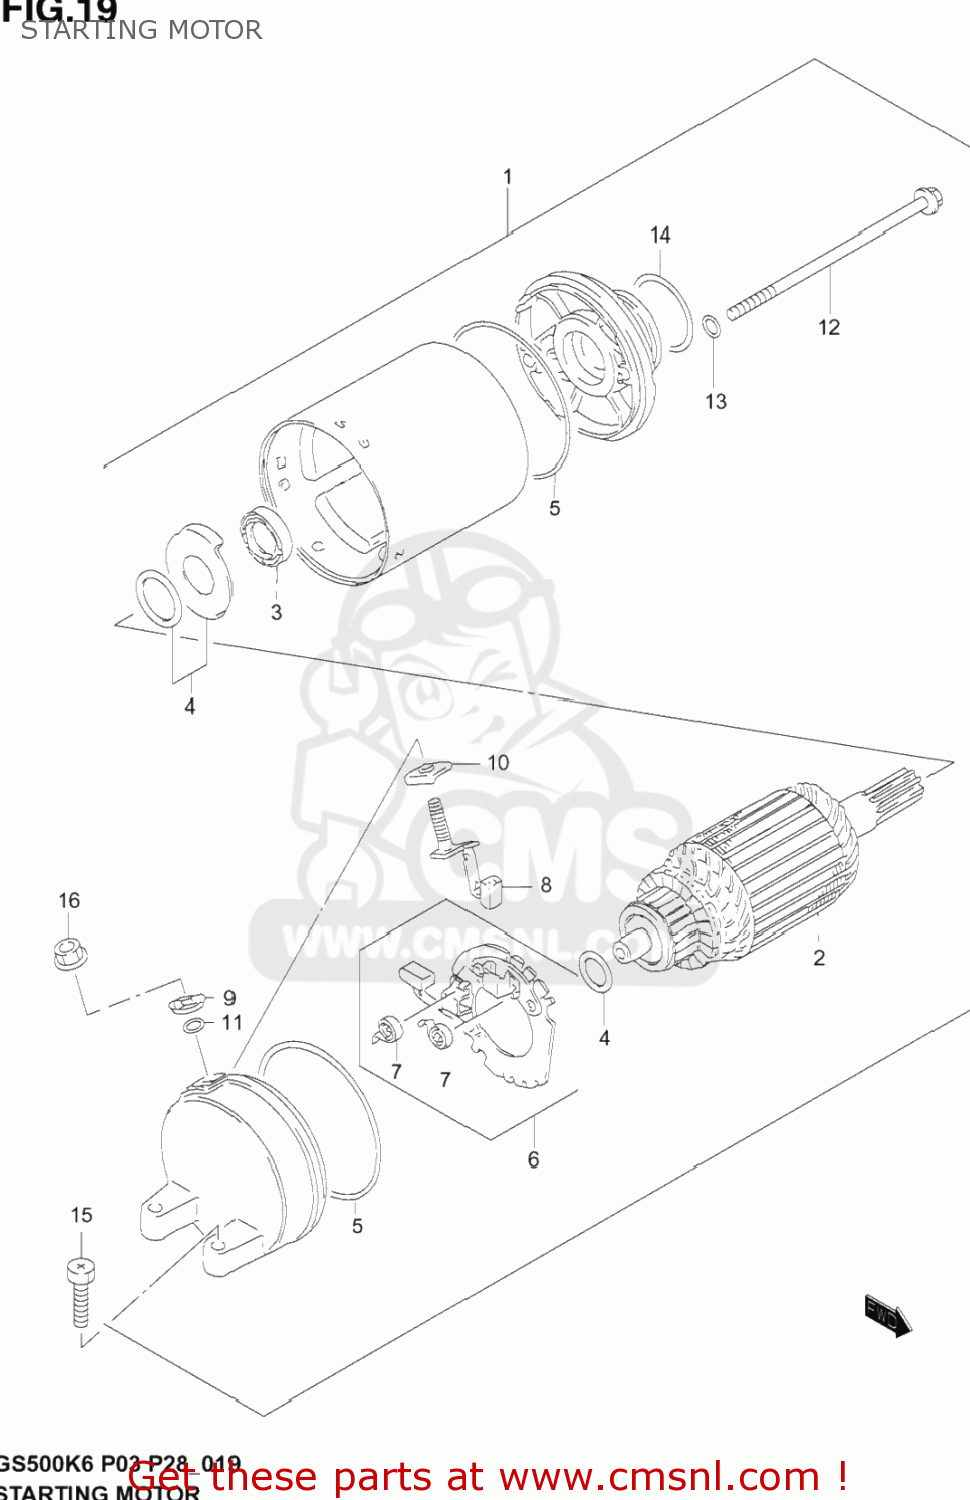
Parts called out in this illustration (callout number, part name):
1	MOTOR ASSEMBLY,STARTING
2	ARMATURE
3	SEAL,OIL
4	SHIM SET,STARTING MOTOR
5	O RING
6	HOLDER,BRUSH
7	SPRING
8	BRUSH SUB ASSY,STARTING MOTOR
9	BUSHING
10	BUSH,B
11	O RING
12	BOLT
13	O RING
14	O RING(D:3,ID:24.5)
15	SCREW (6X25)
16	NUT
